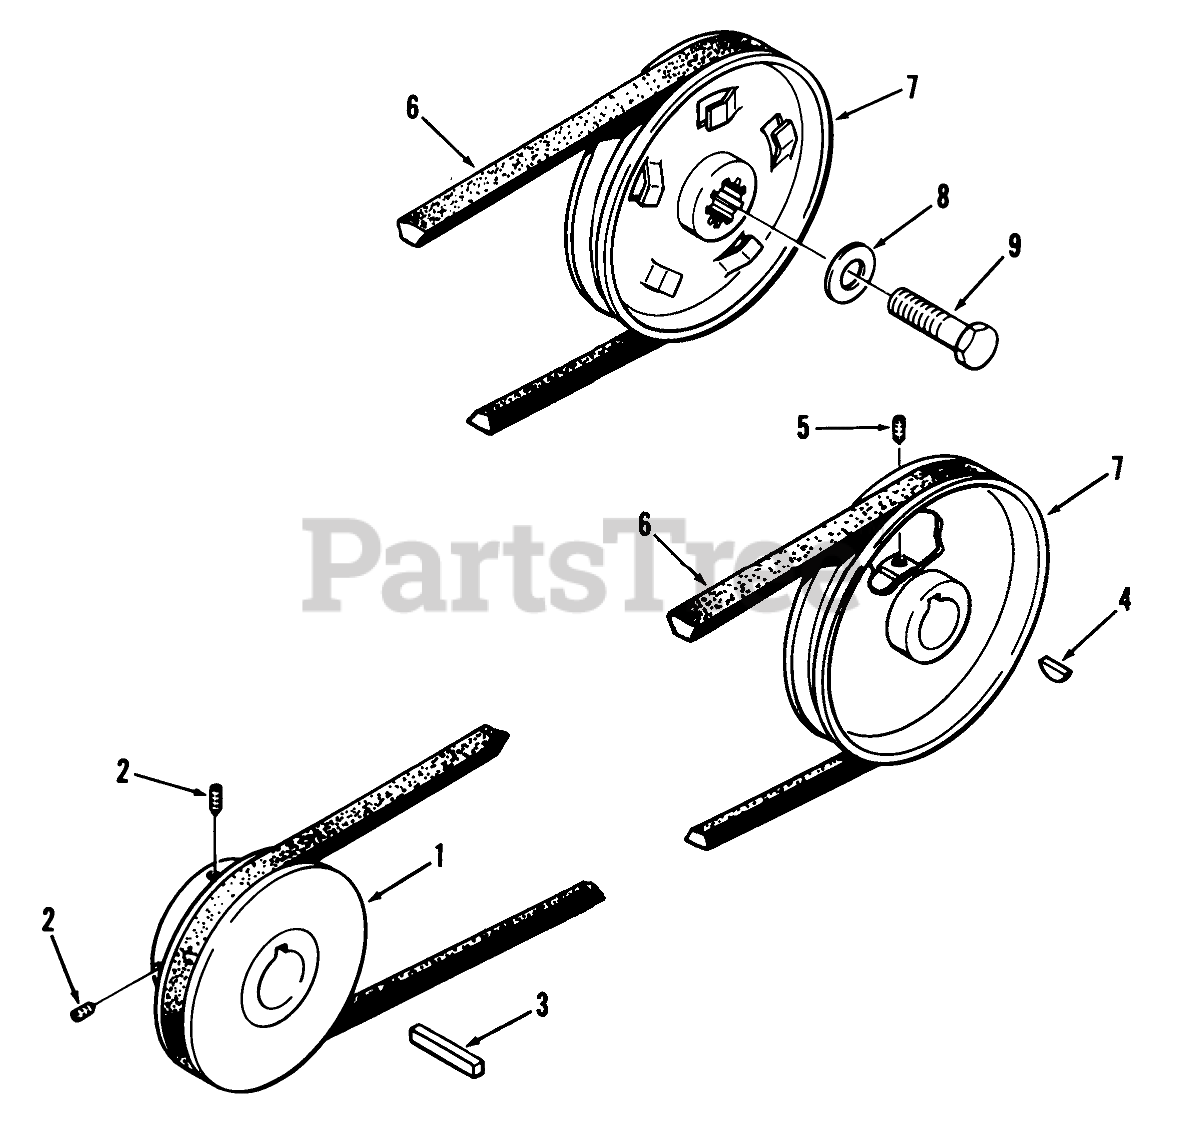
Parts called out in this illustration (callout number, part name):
1	PULLEY-ENGINE
1	PULLEY
5	Set Screw 5/16-18 X 5/8
6	V BELT
6	V-BELT
7	PULLEY-TRANSMISSION
8	WASHER
